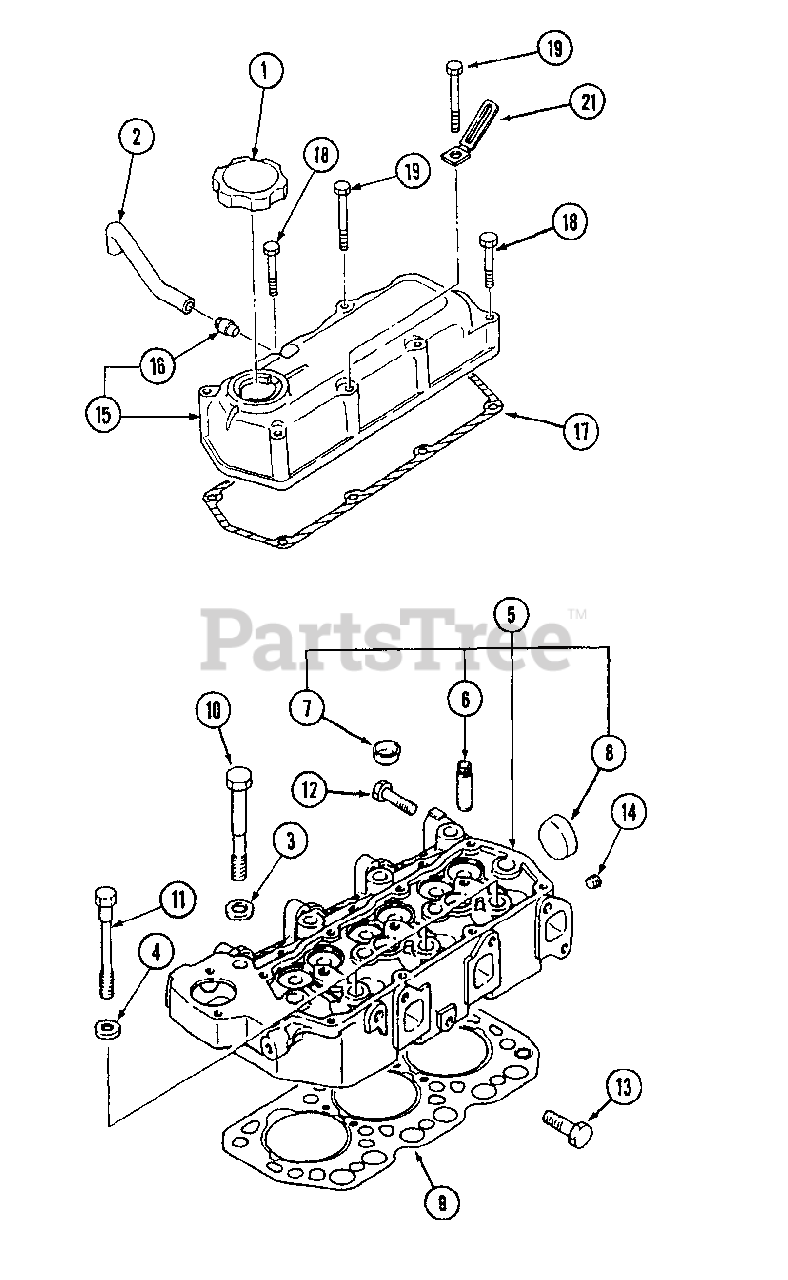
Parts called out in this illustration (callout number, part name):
1	Cap, Oil Filler
2	Pipe, Air Breather
5	Head Ass'y., Cylinder
6	Guide, Valve
7	Cap, Sealing
8	Cap, Sealing
9	Gasket, Cylinder Head
10	Bolt, Cylinder Head
11	Bolt, Cylinder Head
14	Plug, Taper
15	Cover Ass'y., Rocker
16	Pipe
17	Gasket, Rocker Cover
